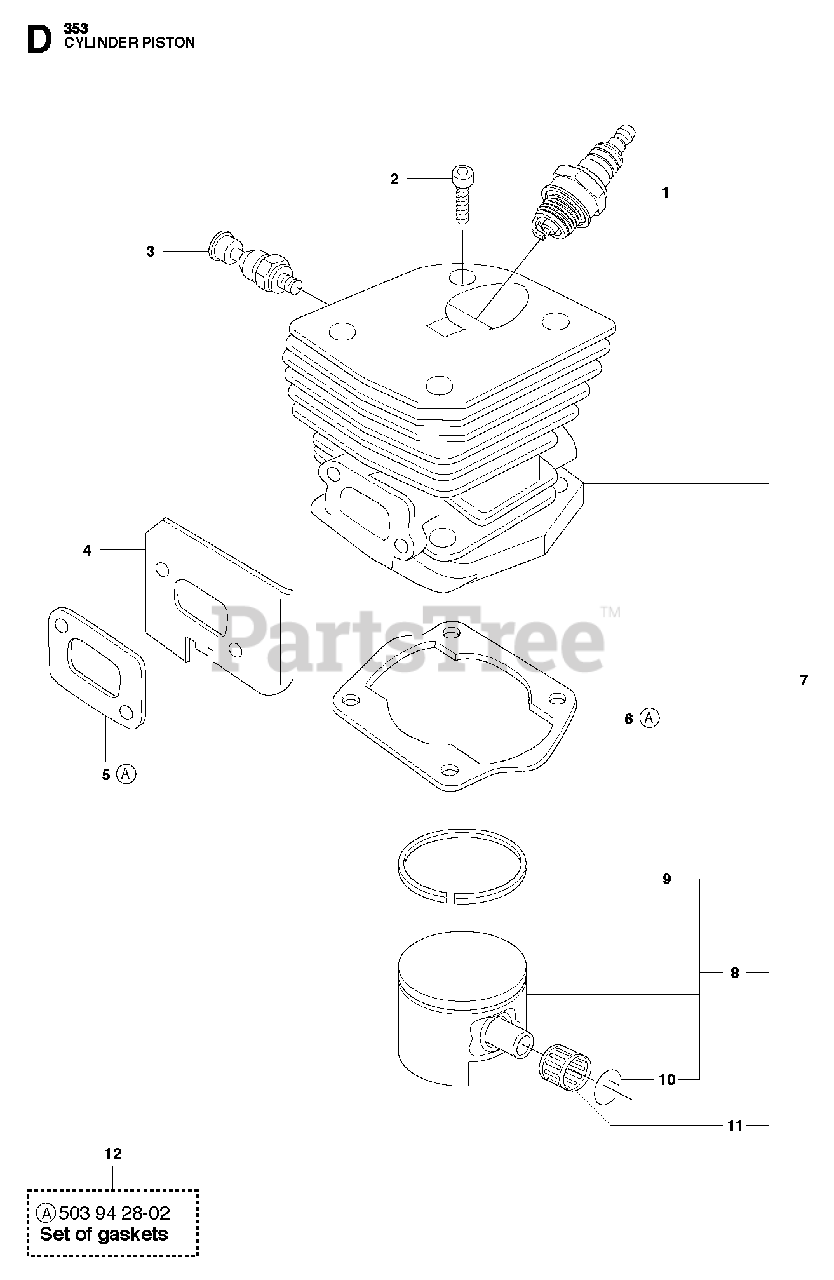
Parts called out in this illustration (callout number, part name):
1	SPARK PLUG RCJ7Y
2	SCREW MC6S 5X25
3	DECOMPRESSION VALVE
5	GASKET
6	GASKET
7	CYLINDER ASSY
8	PISTON
9	%PISTON RING
10	LOCKING RING
11	SUPPORT BUSHING
12	GASKET SET
